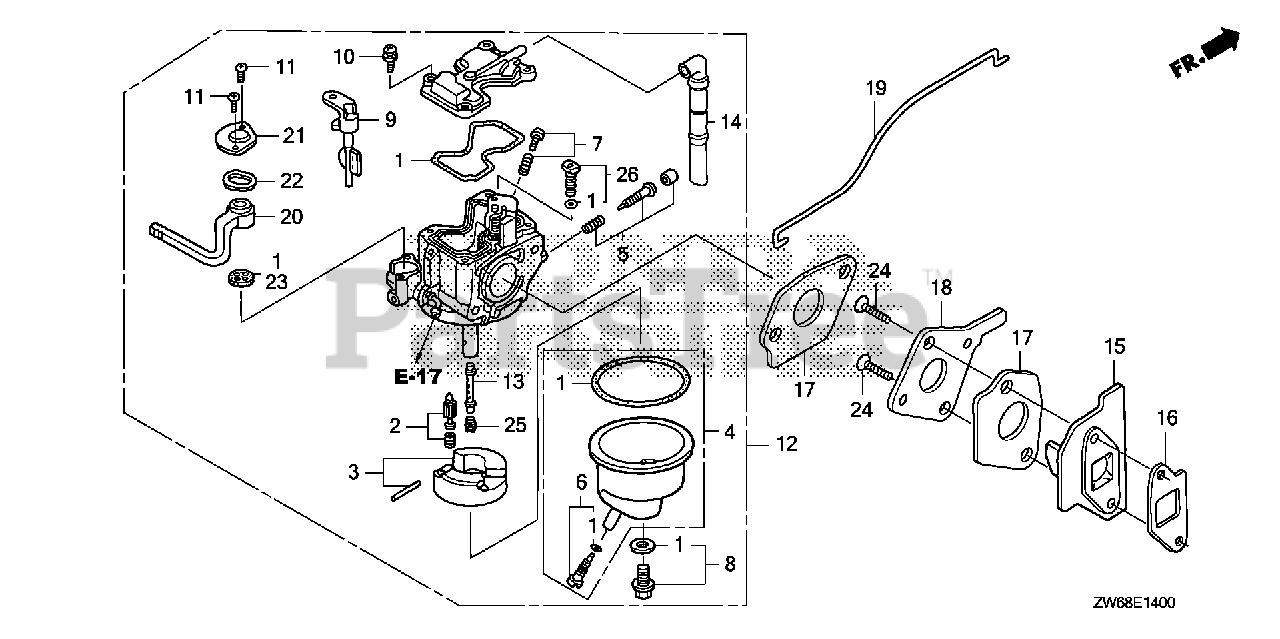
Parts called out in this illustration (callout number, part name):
1	GASKET SET
2	VALVE SET, FLOAT (SEAT NOT INCLUDED)
4	CHAMBER SET, FLOAT
6	SCREW SET, DRAIN
8	SCREW SET
9	LEVER SET, CHOKE
10	SCREW, PAN
11	SCREW, PAN (3X6)
12	CARBURETOR ASSY. (BF33G A)
13	NOZZLE, MAIN
14	TUBE ASSY., AIR VENT
15	INSULATOR, CARBURETOR
16	GASKET, INSULATOR
17	GASKET, CARBURETOR
18	PLATE, CARBURETOR JOINT
19	ROD, CHOKE
20	LEVER, PETCOCK
21	PLATE, LEVER SETTING
22	SPRING, PETCOCK LEVER
23	GASKET, PETCOCK
24	SCREW, FLAT (5X20)
25	JET, MAIN (#55)
25	JET, MAIN (#58)
25	JET, MAIN (#60)
25	JET, MAIN (#62)
26	JET SET, PILOT (#35)
